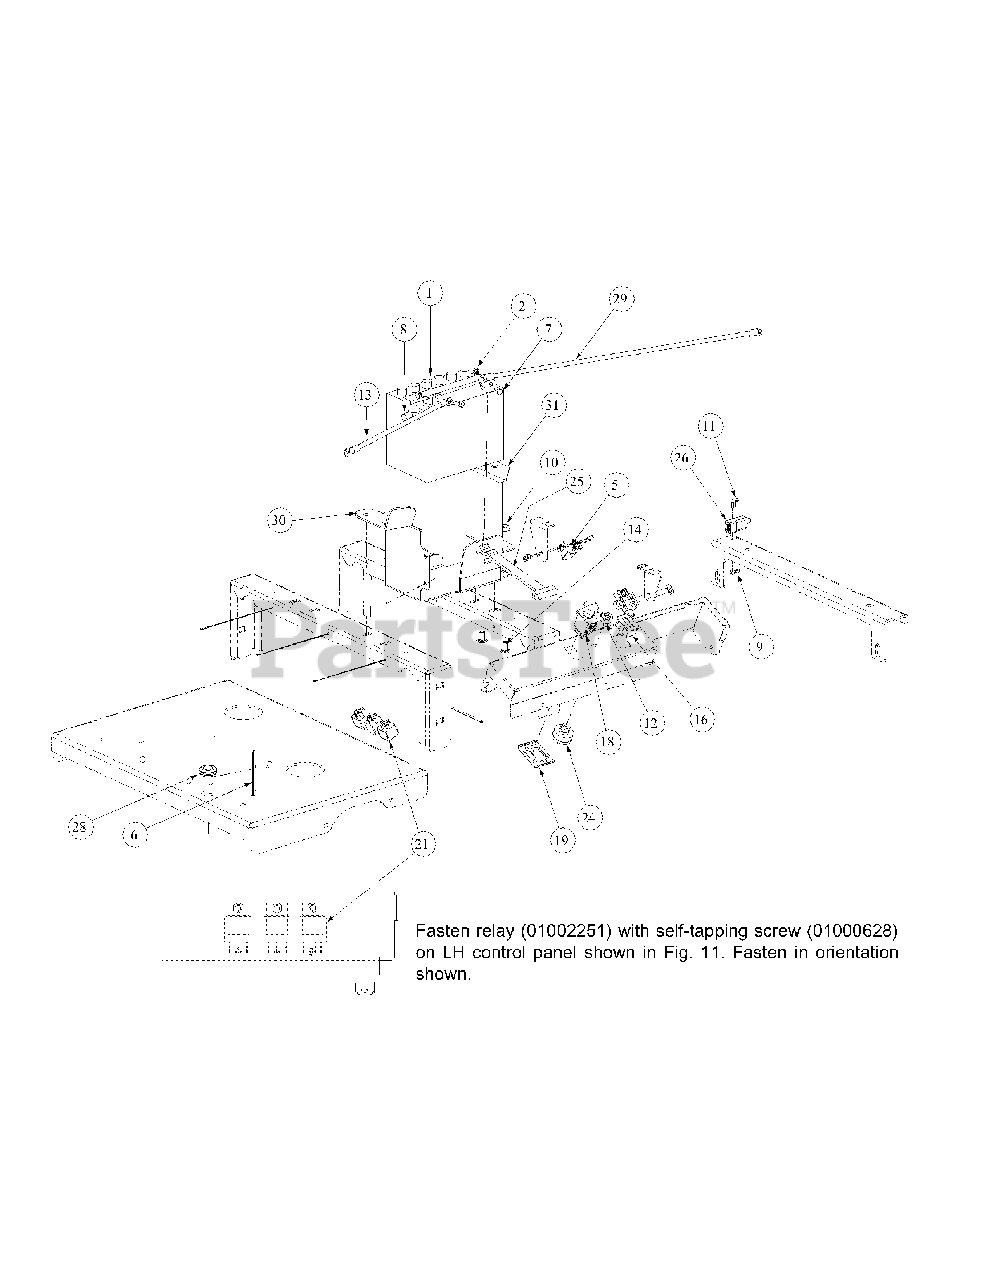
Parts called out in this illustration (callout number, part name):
1	Battery, 12V 225CCA 30 Min
2	Lock Nut, 1/4-20
5	Switch, Safety
6	Tie, Cable, 3/16 x .05 x 7.4"
7	Screw, Hex, Cap, 1/4-20 x .75
8	Boot, 1" OD Rubber Battery-PST, Red
9	Lock Nut, Nylon Insert
10	Nut, Hex, Flange Lock, 3/8-16
11	Screw, Phillips Head, Machine, 10-32 x 5/8
12	Nut, W/Cap, 5/8-32 Ignition
13	Cable, Battery, Red, 15"
14	Carriage Bolt, 3/8-16 x .75 LG.
16	Meter, Hour
18	Switch, Electric, PTO
19	Bracket, PTO Switch Retainer
21	Relay, 12V 40A
24	Switch, Ignition, 6 Pin
24	Key, Ignition
25	Strap, Battery
26	Switch, Plunger
28	Grommet, .75 ID
29	Cable, Battery Red, 24"
30	Mount Bracket, Battery
31	Mount Bracket, Battery
